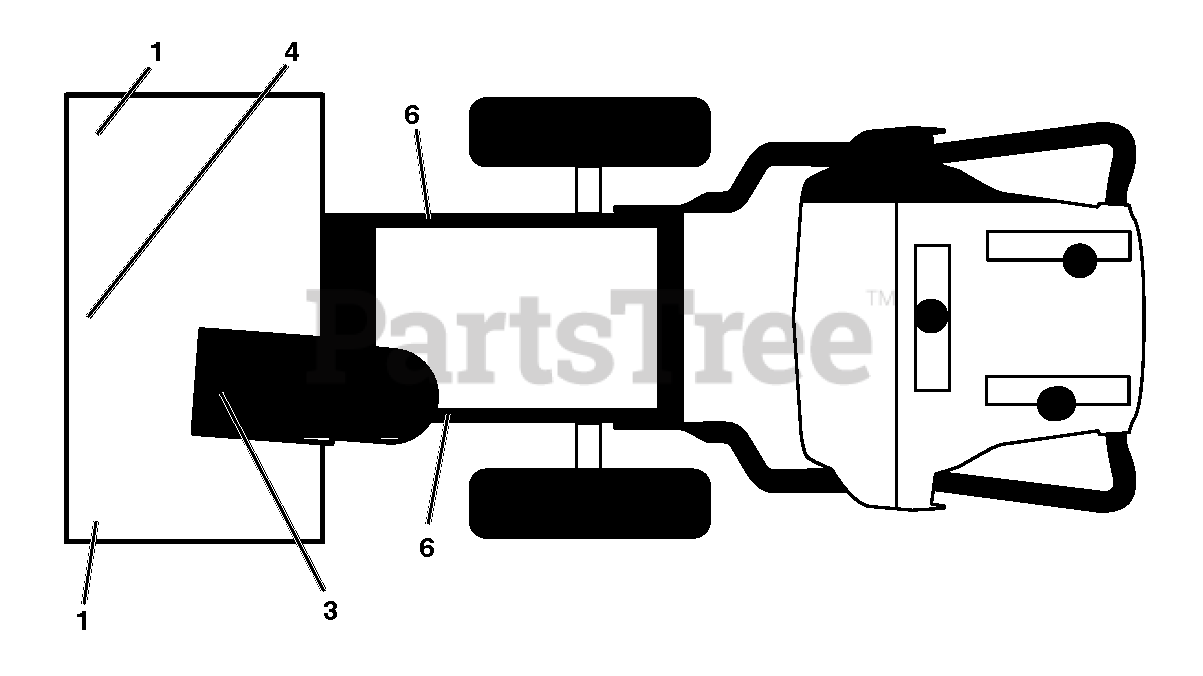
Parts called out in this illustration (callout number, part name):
1	DECAL.AUGER.SAFETY.
3	DECAL.CHUTE.SAFETY.
4	DECAL.AUGER."
6	DECAL.BELT.GUARD.
